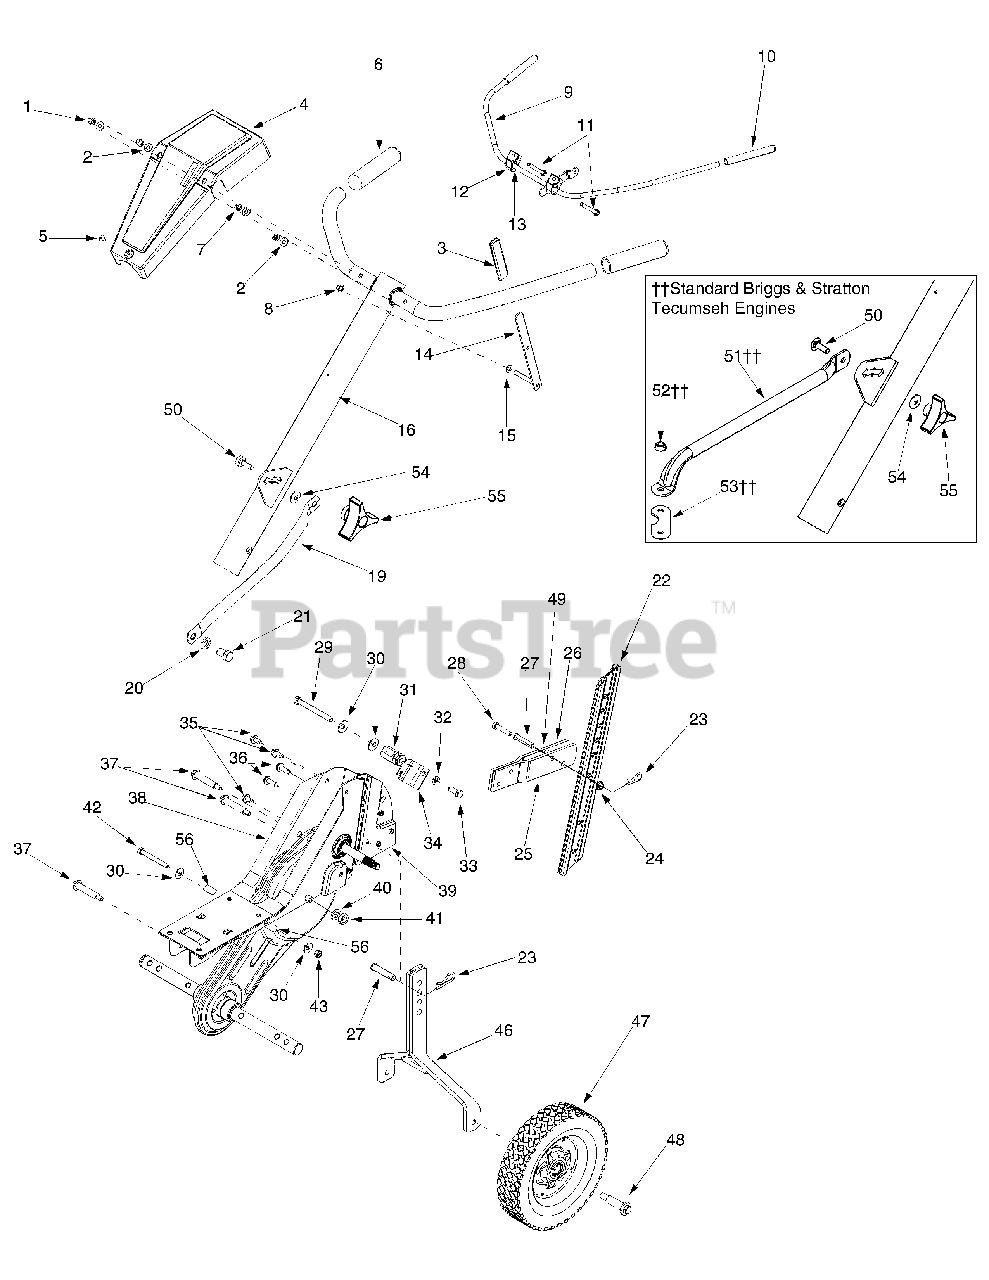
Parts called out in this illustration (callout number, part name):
1	Acorn Lock Nut 1/4-20
2	Flat Washer.271" I.D. x.630" O.D.
3	Reverse Handle Grip
4	Handle Cover w/o throttle
5	Truss Mach. Scr. #10 x 1/2" Lg.
6	Handle Grip
7	Hex Nut 1/4-20 Gr.2
8	Cap Speed Nut
9	Clutch Handle Assembly
10	Clutch Grip
11	Hex Bolt 1/4-20 x 2.25" Lg. Gr.5
12	Clutch Handle Holder
13	Flat Washer.385" I.D. x.62" O.D.
14	Reverse Handle Ass’y
15	Flat Washer.344" I.D. x.62" O.D.
20	Lock Washer 1/2
21	Hex Bolt 1/2-20 Gr. 5
22	Depth Bar
23	Cotter Pin
24	Hex Flange L-Nut 5/16-18 Thd. Gr.5
25	Tail Piece Bracket (L.H.)
26	Tail Piece Bracket (R.H.)
27	Clevis Pin
28	Hex Bolt 5/16-18 x 1.5" Lg.
29	Hex Bolt 5/16-18 x 3" Lg.
30	Wash. Bell.340" I.D. x.872" O.D.
31	Spec. Hex Nut
32	L-Wash. 5/16" I.D.
33	Hex Bolt 5/16-18 Gr. 5
34	Cable Guide Bracket
35	Hex Washer Screw 5/16-18 x.62" Lg.
36	Hex Wash. Hd. TT-Tap Scr.
37	Shdl. Bolt 5/16-18
40	Lock Washer 7/16
41	Jam Nut 7/16-20 Gr. 2
42	Hex Bolt 5/16-18 x 2.75" Lg.
43	Hex Nylon Nut 5/16-18 Thd.
46	Wheel Hanger Bracket Assembly
47	Wheel Ass’y 8" x 1.75"(Plastic)
47	Wheel Ass’y 8" x 1.75" (Steel)
48	Shoulder Screw.496 I.D. x 1.445 O.D.
49	Spacer
50	Carr. Bolt 5/16-18 x 1
52	Hand Knob
53	Engine Brkt.
53	Spacer
55	Bell. Wash.34" I.D.
